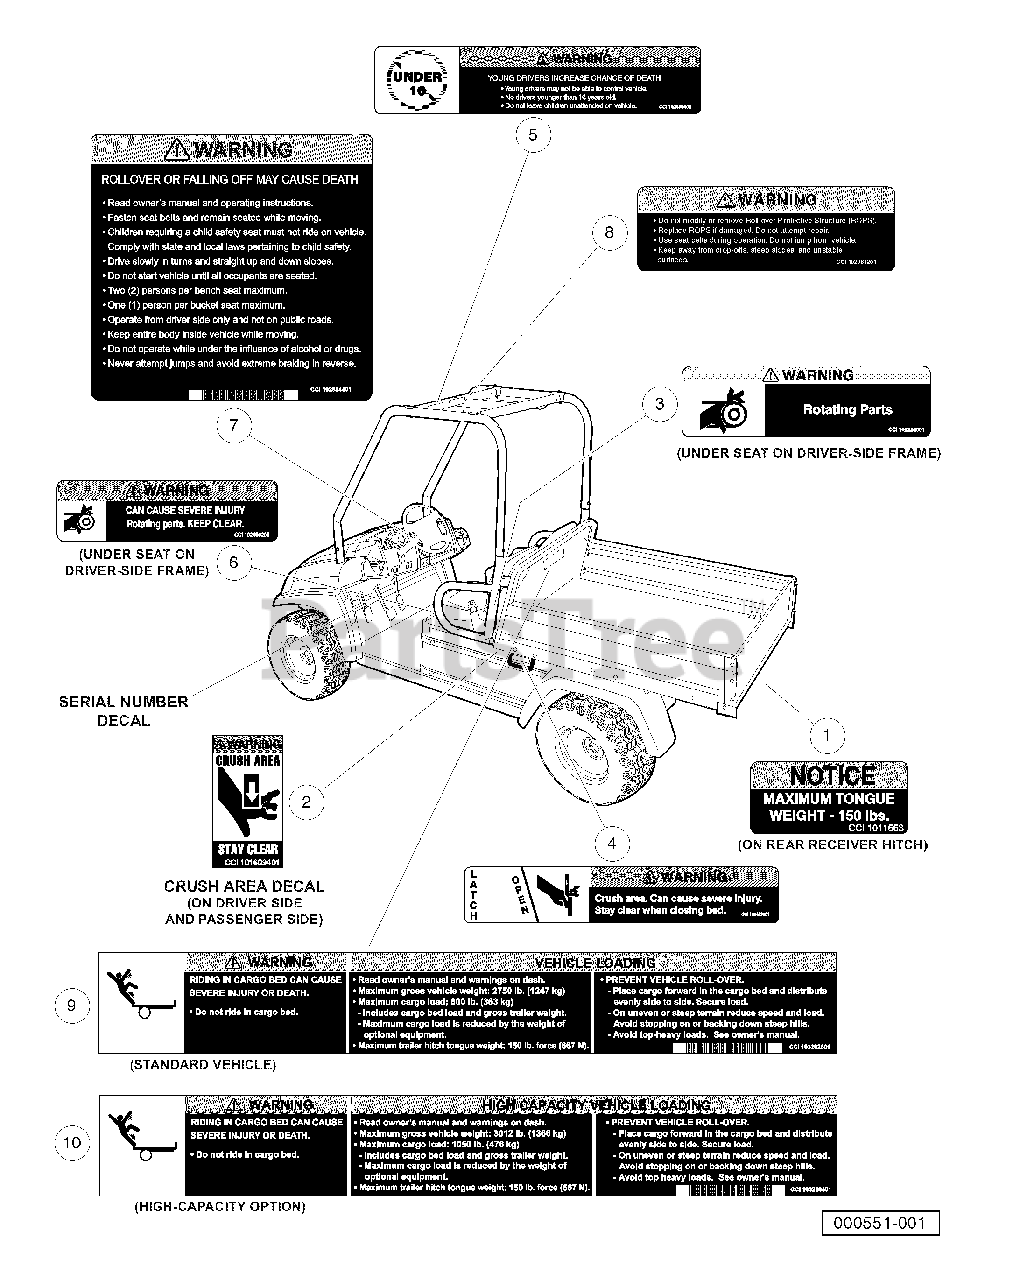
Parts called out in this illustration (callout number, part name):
1	Decal, Trailer Hitch
2	Decal, Crush Area Warning
3	Decal, Rotating Parts Warning
4	Decal, Bed Crush Area Warning
5	Decal, Young Driver Warning
6	Decal, Rotating Parts Warning
7	Decal, Operator Warning
8	Decal, Warning, AWD ROPS
9	Decal, Vehicles Loading, Standard Vehicle
10	Decal, Loading Capacity, High Capacity Option
